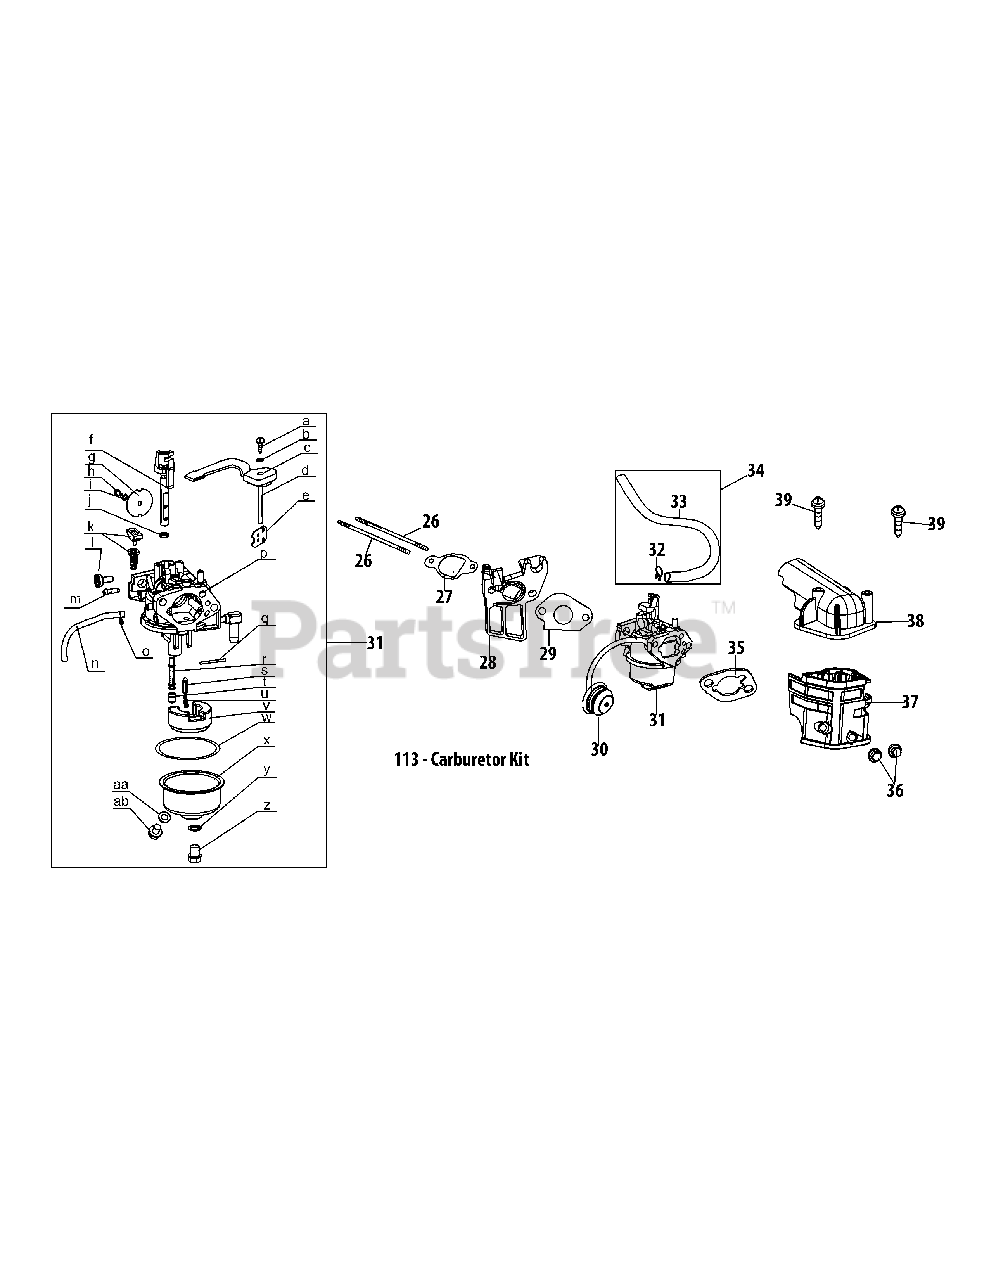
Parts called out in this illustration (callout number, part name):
26	Carburetor Stud Bolt
27	Carburetor Insulator Gasket
28	Carburetor Insulator
29	Carburetor Gasket
30	Primer Bulb
31	Carb Assembly
32	Hose Clamp
33	Fuel Line Hose
34	Fuel Line Kit
35	Carburetor Gasket Plate
37	Intake Heater Box Base
38	Intake Heater Box
39	Self Tapping Bolt
113	Carburetor Kit
